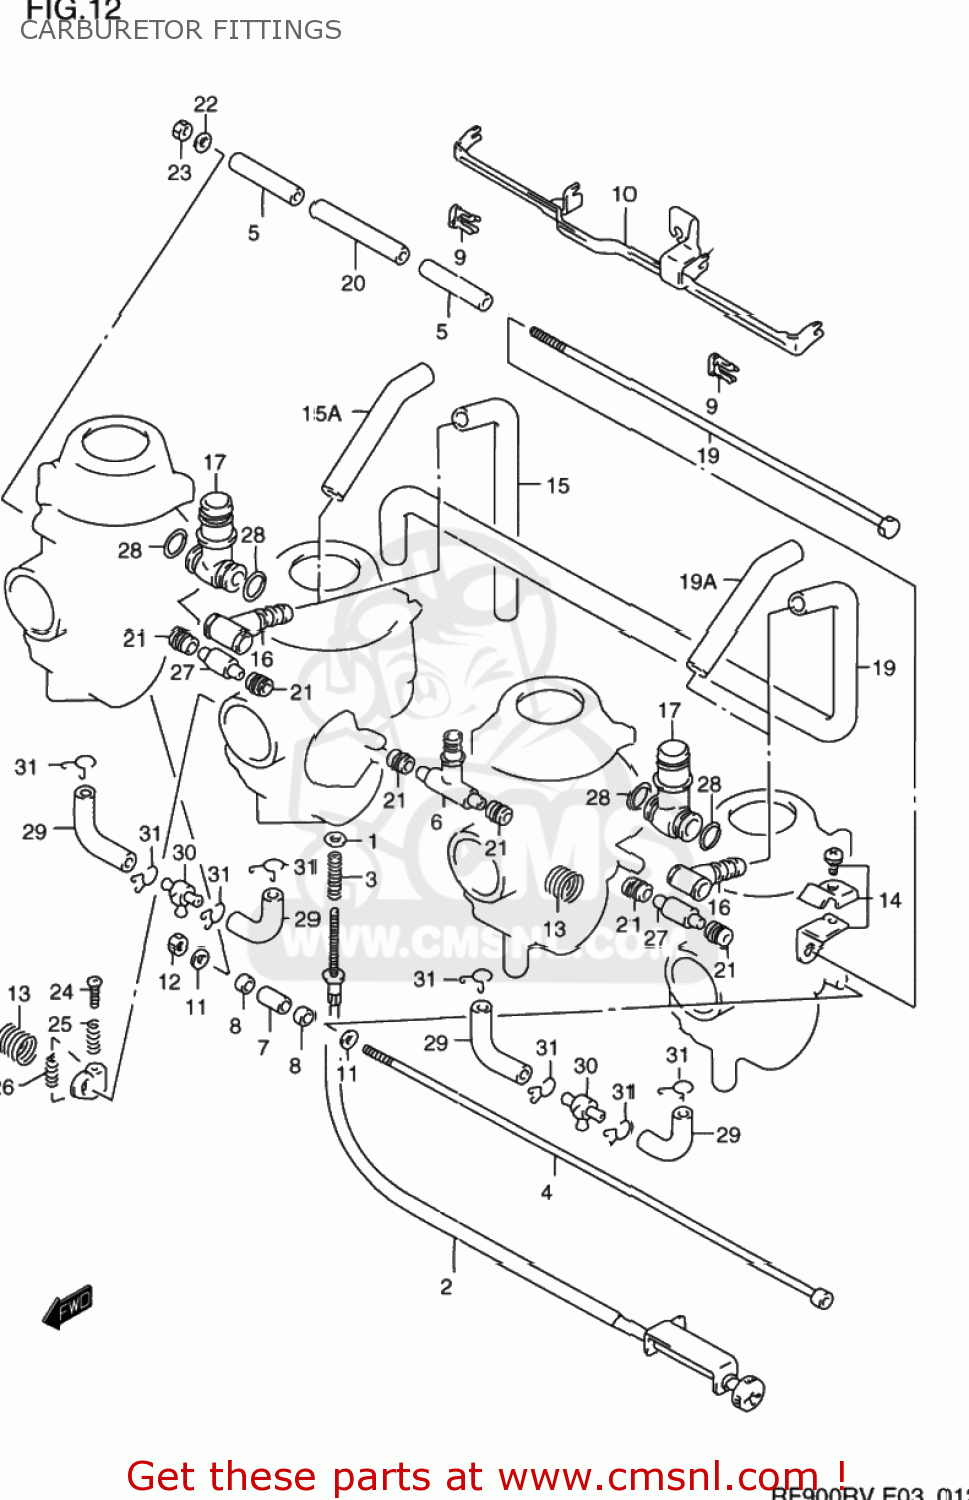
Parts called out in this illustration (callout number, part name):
1	WASHER
2	SCREW,ADJUST
3	SPRING
4	BOLT
5	RING
6	NIPPLE
7	RING
8	RING
9	HOLDER
10	LEVER,STARTER
11	WASHER
12	NUT
13	SPRING
14	BRACKET ASSY
15	HOSE
15A	HOSE
16	3 WAY
17	NIPPLE
18	BOLT
19	HOSE
19A	HOSE
20	RING
21	SEAL
22	WASHER
23	NUT
24	SCREW
25	SPRING
26	SPRING,THROTTLE SCREW
27	PIPE
28	O-RING
29	HOSE
30	NIPPLE
31	CLIP
